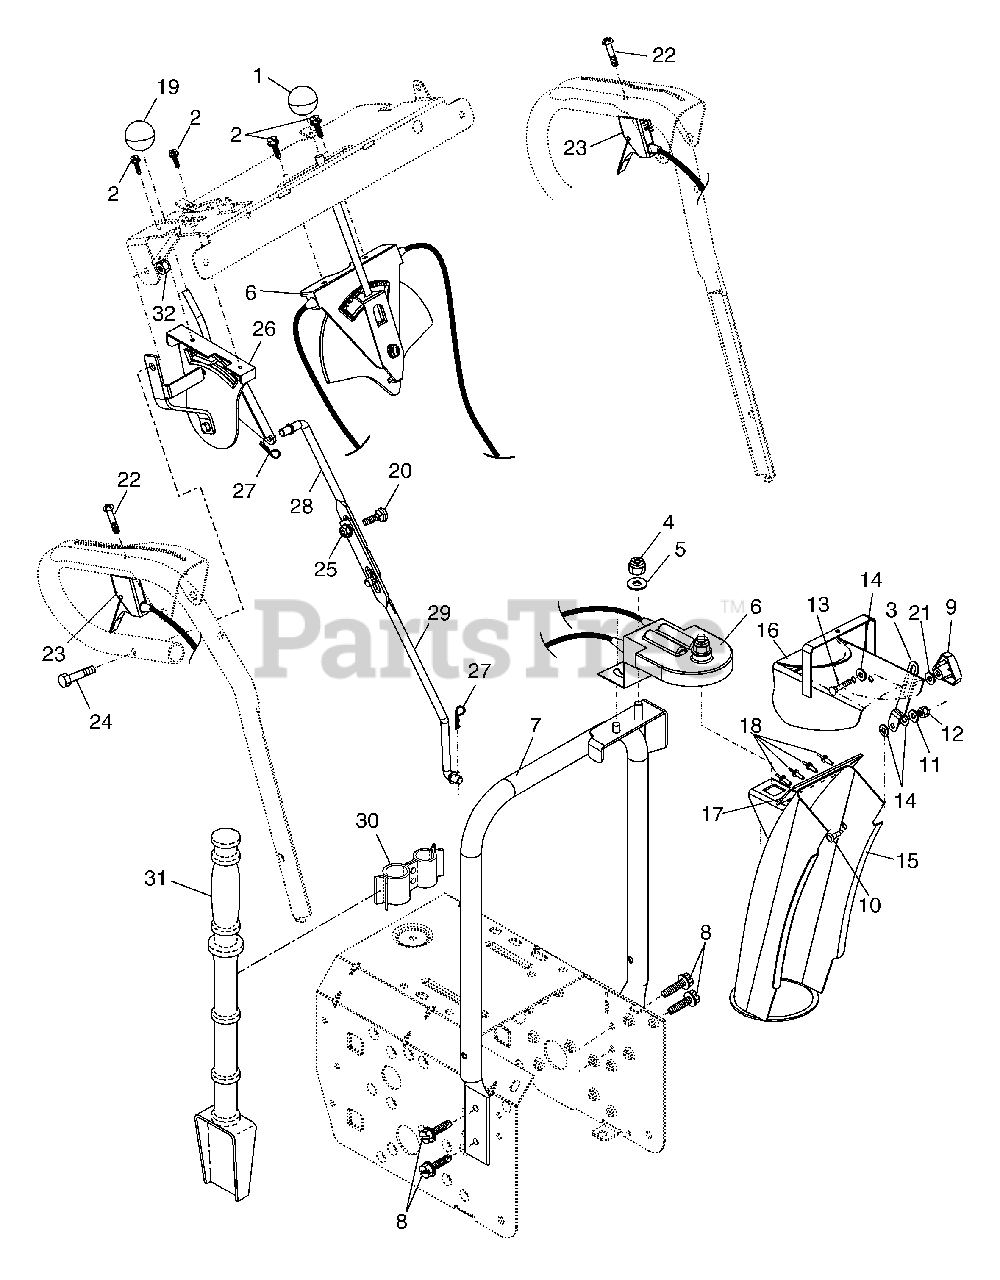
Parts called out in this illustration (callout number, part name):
1	Knob, Lever
2	Screw #10-24 x 5/8
3	Strap, Slotted
4	Nut, Lock 3/8-16
5	Washer, Flat 3/8
6	Control Assembly, Chute Rotater
7	Support, Pivot
8	Screw, Hex Head 5/16-18 x 3/4
9	Knob, Deflector
10	Bolt, Shoulder
11	Washer, Flat 1/4
12	Nut, Lock 1/4-20
13	Bolt, Carriage 5/16-18 x 5/8
14	Washer, Nylon
15	Chute Assembly
16	Deflector Assembly
17	Seal, Deflector
18	Rivet, Blind
19	Knob, Speed Control Lever
20	Bolt, Carriage 5/16-18 x 3/4
21	Washer, Flat
22	Screw #10-24 x 1-1/2
23	Control Assembly, Power Steering
24	Screw, Hex Head 5/16-18 x 1-3/4
25	Nut, Lock 5/16-18
26	Lever Assembly, Speed Control
27	Retainer, Hairpin
28	Rod, Upper, Speed Control
29	Rod, Lower, Speed Control
30	Clamp, Clean-Out Tool
31	Tool, Clean-Out
32	Nut, Lock 5/16-18
